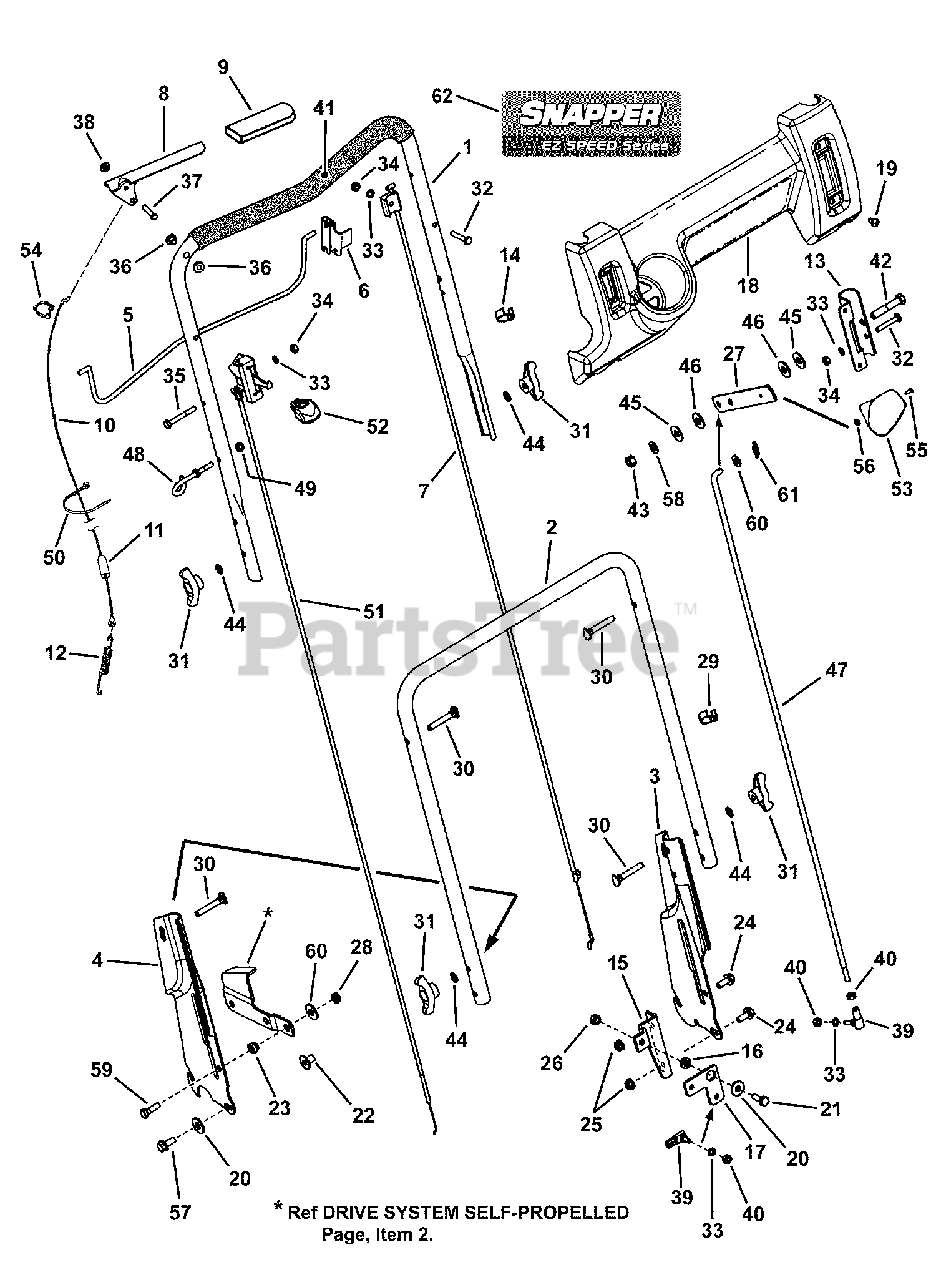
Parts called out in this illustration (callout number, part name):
1	HANDLE, Upper
2	HANDLE, Middle
3	HANDLE, Lower LH (Adjustable)
4	HANDLE, Lower RH (Adjustable)
5	BAIL, OPC Control
6	CLIP, Zone Control
7	* CABLE, Zone Control (56-5/16" Long)
8	HANDLE, Clutch
9	GRIP, International Symbol
10	CABLE, Clutch Control (41-1/4" Long)
11	COVER, Vinyl
12	SPRING, Clutch - 21S
13	BRACKET, Shift
14	TIE, Wire, 1.29 long, black
15	BRACKET, Bell Crank
16	SPACER, .33 x .63 x .156
17	BELL CRANK
18	CONTROL PANEL (w/o Electrical Switch Hole)
19	SCREW, 1/4-20 x 1/2" Pan Head Self-Tap (Torx)
20	WASHER, .33 x .88 x .09 Flat
21	SCREW, 5/16-18 x 7/8" Hex Head Cap, GR 5
22	TEENUT, 5/16-18
23	BUSHING, Differential, .328 x .625 x .41
24	BOLT, 5/16-18 x 3/4" Hex Flange Lock GR 5
25	NUT, 5/16-18 Hex Flange Lock, GR 5
26	NUT, 5/16-18 Hex Center Lock
27	LEVER, Shift
28	NUT, 5/16-24 Hex Center Lock GR 5
29	CLIP, Wiring Harness
30	SCREW, 5/16-18 x 1-7/8" Curved Head GR 2
31	KNOB, 5/16-18 Wing (Black)
32	SCREW, 1/4-20 x 1-1/2" Hex Head Cap GR 5
33	WASHER, 1/4" Internal Tooth Lock
34	NUT, 1/4-20 Hex
35	SCREW, 1/4-20 x 2" Hex Head Cap, GR 5
36	BUSHING, .27 x .35 x .4 Flange
37	PIN, 1/4 x 1-1/2"
38	PUSH-NUT, 1/4"
39	BALL JOINT, 1/4-28
40	NUT, 1/4-28 Hex
41	FOAM GRIP, 18.75" long
42	SCREW, 3/8-16 x 2" Hex Head Cap, GR 5
43	NUT, 3/8-16 Hex Center Lock
44	WASHER, 5/16" Internal Tooth Lock
45	WASHER, 7/16" Flat
46	WASHER, Nylon
47	ROD, Speed Control (1/4-28 thread)
48	GUIDE, Rope (1/4-20 thread)
49	NUT, 1/4-28 Hex GR 5 or B
50	CABLE-TIE, 7"
51	THROTTLE CONTROL, 6.0 KWV (53.25")
52	THROTTLE KNOB (Red)
53	KNOB, Shift (Red)
54	CLAMP, 7/8" Double Cable
55	SCREW, #8-32 x 1/2" Cross Recess Filister Head Machine
56	NUT, #8-32 Hex
57	SCREW, 5/16-18 x 1-1/4" Hex Washer Head Self-Tap
58	WASHER, Belleville
59	SCREW, 5/16-24 x 1" Hex Head Cap GR 5
60	WASHER, 11/32" Flat
61	COTTER PIN, 5/16 Self Lock
62	DECAL, Easy Speed, Control Panel
